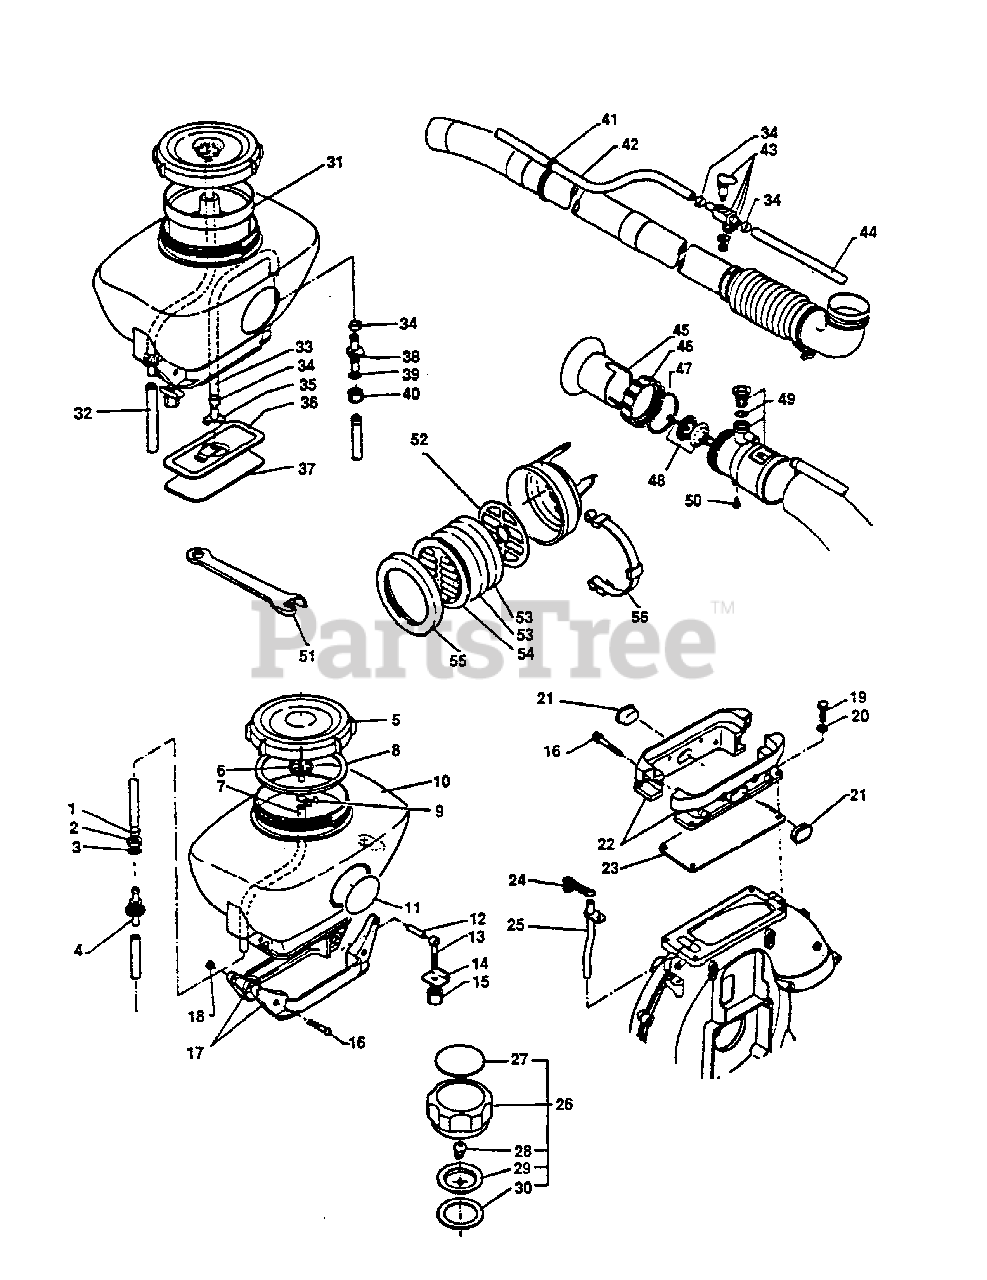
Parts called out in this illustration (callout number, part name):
1	CLAMP
2	NUT - 12
3	WASHER - 12
4	CONNECTOR, PIPE
5	CAP, CHEMICAL TANK
6	VENT, TANK
7	HOSE, FLUID
8	GASKET, CAP
9	CLAMP
10	TANK, CHEMICAL
11	LABEL
16	SCREW - 5X30
17	HOLDER
19	BOLT - 6X20
20	WASHER - 6
22	CLAMP KIT
25	HOSE, AIR
26	CAP ASSY
27	LABEL - FUEL MIX
29	HOLDER, VENT
30	GASKET, CAP
31	FILTER, CHEMICAL TANK
32	HOSE, AIR
33	HOSE, FLUID
34	CLIP - 13
35	MOUTH, SUCTION
36	Plate, Base
38	CONNECTOR, PIPE
40	NUT, CONNECTOR
41	CLIP
42	HOSE
43	VALVE ASSY
44	HOSE, FLUID
49	CONTROL, VOLUME
50	SCREW - 5X12
51	SPANNER - 10X21mm
52	RETAINER, AIR FILTER
53	FILTER, AIR
54	COVER, AIR FILTER
55	COVER, AIR FILTER
56	CLAMP
